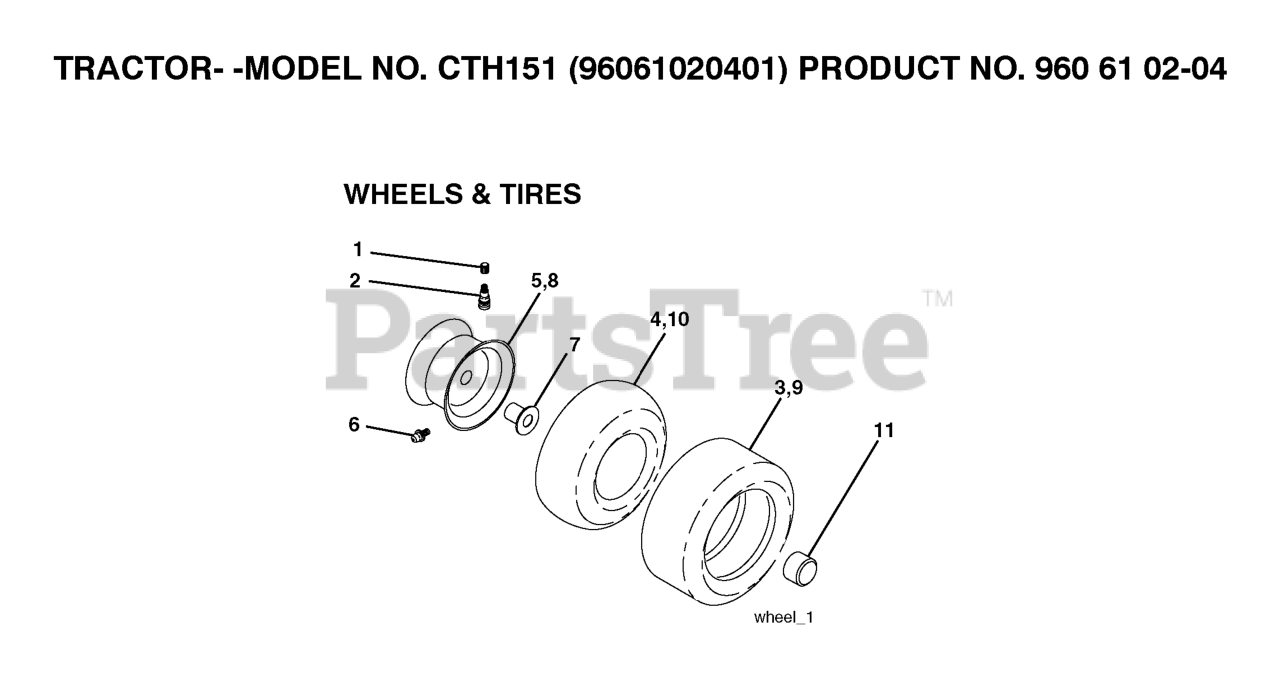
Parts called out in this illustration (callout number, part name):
2	VALVE STEM LT
3	TIRE HEAVY DUTY
4	TUBE.5.3/4.5/6
5	RIM ASM 6" FRONT SILVER
6	FITTING LT
7	BEARING T
8	RIM ASM 8" REAR SILVER
9	TIRE HEAVY DUTY
10	TUBE
11	CAP, AXLE BLK
